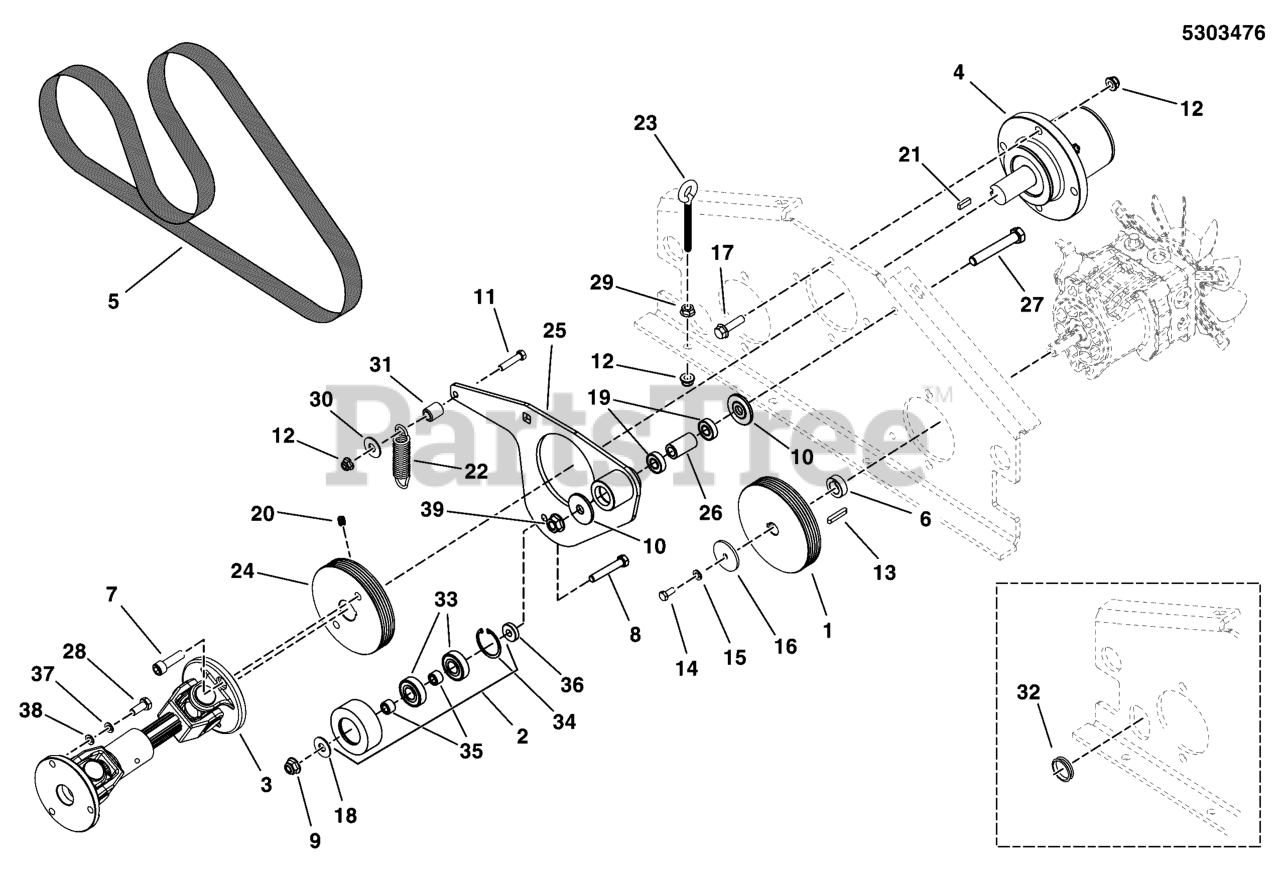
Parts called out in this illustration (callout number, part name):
1	PULLEY, POLY V "K" SECTION 5K4.5 X 15MM
2	ASSM, PULLEY, FLAT BACKSIDE IDLER, 2.75 (5102806)
3	DRIVE SHAFT ASM, IS2500Z
4	ASSM, CARRIER BEARING
5	BELT, POLYRIB, 49.75, 5 RIB
6	BUSHING, 15MM X 25MM X 8.6MM - KEYED
7	BOLT, 3/8-16 X 1-1/4 SHCS
8	BOLT, 3/8-16 X 2-1/4" GD5 CZ
9	NUT, 3/8-16 HEX NYLOCK FLANGE
10	SPACER, IDLER ARM, 1/2, PM
11	BOLT, 5/16-18 X 1-1/4 GD5 YZ
12	NUT, 5/16-18 HEX NYLOCK FLANGE
13	KEY, 5MM SQ. W/ RADIUS
14	CAPSCREW-HEX HEAD M6-1.0X20MM W/PATCH,CZ
15	WASHER, 1/4 LOCK
16	WASHER, .265 X 1.50 X .109, YZ
17	BOLT, 3/8-16 X 1-1/4, FLANGE, GD 5, CZ
18	WASHER, 3/8 USS
19	BEARING, BALL, AXLE
20	SET SCREW, 3/8-16 X 1/2 KNURLED
21	KEY, 1/4 SQ X 1
22	SPRING-EXT, .930 ODX4.020LGX.120WR, BLK
23	EYE BOLT,5/16-18 X3.5,2.13THRD,.55EYE,CZ
24	PULLEY, POLY V "K" SECTION 5K4.25 X 1"
25	WELD, IDLER ARM - BLK
26	SPACER, .52 X .84 X 1.53, PM
27	BOLT, 1/2-13 X 3-1/4, HEX HD, GD5, CZ (SV)
28	BOLT, M8-1.25 X 20MM GD8.8
29	NUT, 5/16-18 HEX SERRATED FLANGE (SMALL)
30	WASHER, 5/16 USS
31	SPACER, .38 X .50 X .27, CZ
32	GROMMET, 1-1/2" ID FOR 1/4" METAL
33	BEARING, BALL 11/16X1-9/16X15/32
34	SNAP RING, INTERNAL
35	INSERT, BEARING, 17MM X 12MM L
36	SPACER, .39 X 1.00 X .25
37	WASHER, 5/16 LOCK CZ
38	WASHER, 5/16" SAE
39	NUT, Hex Flange, Nylock, 1/2-13
